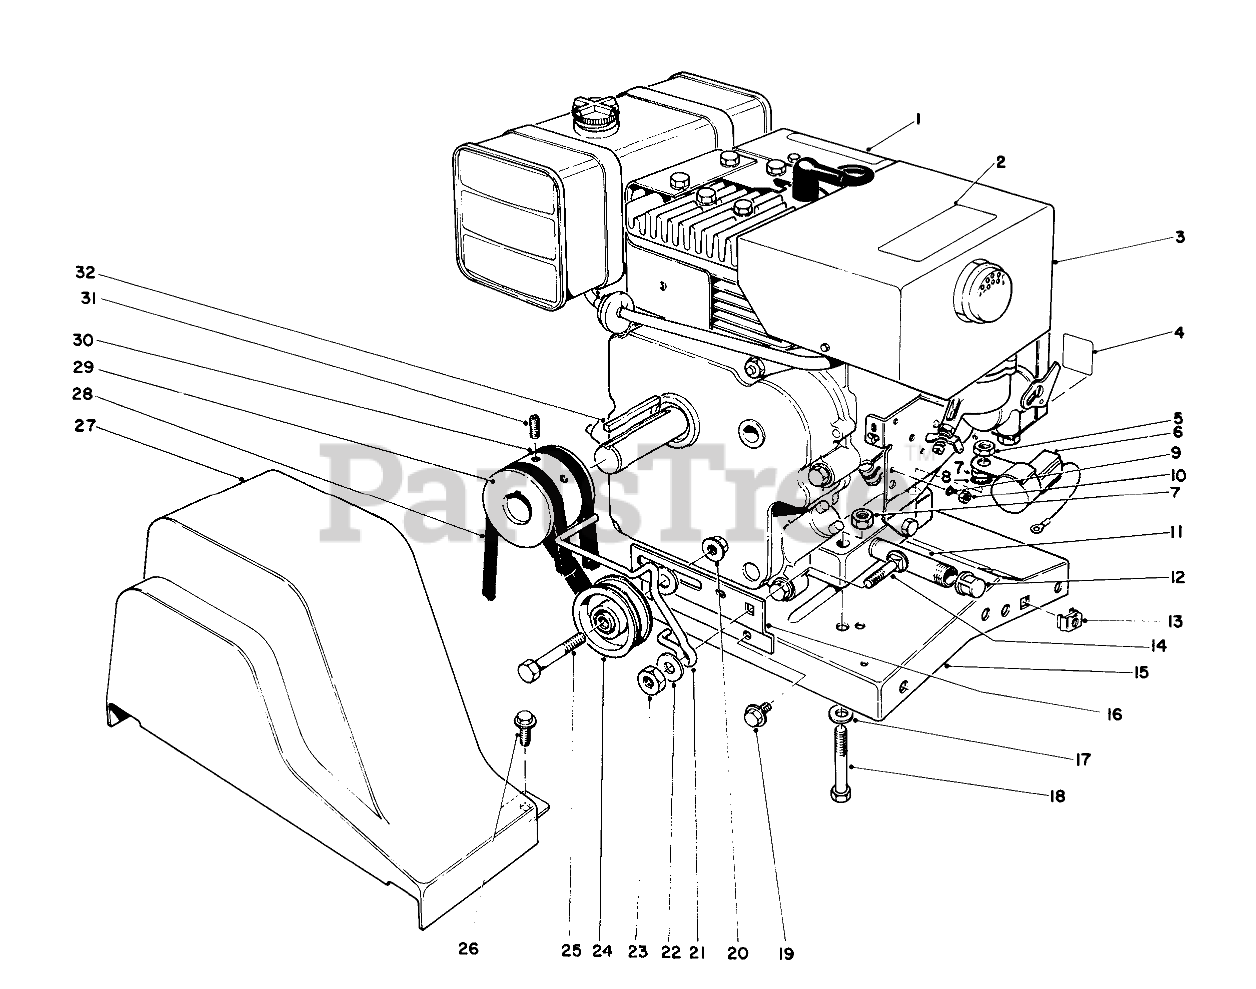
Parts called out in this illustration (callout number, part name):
1	Decal-Hazard
2	Decal Hot Surface Warning
3	Engine
4	CHOKE DECAL
5	NUT-HEX, SIDE DEFORM
6	INTERLOCK MODULE
7	NUT-LOCK, NI
8	WASHER-LOCK, INTERNAL
9	WASHER-LOCK/INT
10	NUT-LOCK
11	NIPPLE-PIPE
12	Pipe Cap
13	RETAINER NUT
14	SCREW-CARR
15	Engine Base
16	BELT IDLER BRKT
17	WASHER-PLAIN
18	SCREW-HH
19	SCREW-HHFTF
20	NUT-HHF, WHIZ
21	BELT GUIDE
22	WASHER-FLAT
23	NUT-HEX
24	PULLEY B
25	SCREW-HH
26	SCREW-HWH
27	BELT GUARD
28	V-BELT
29	ENGINE PULLEY
30	V-BELT
31	Screw-Set
